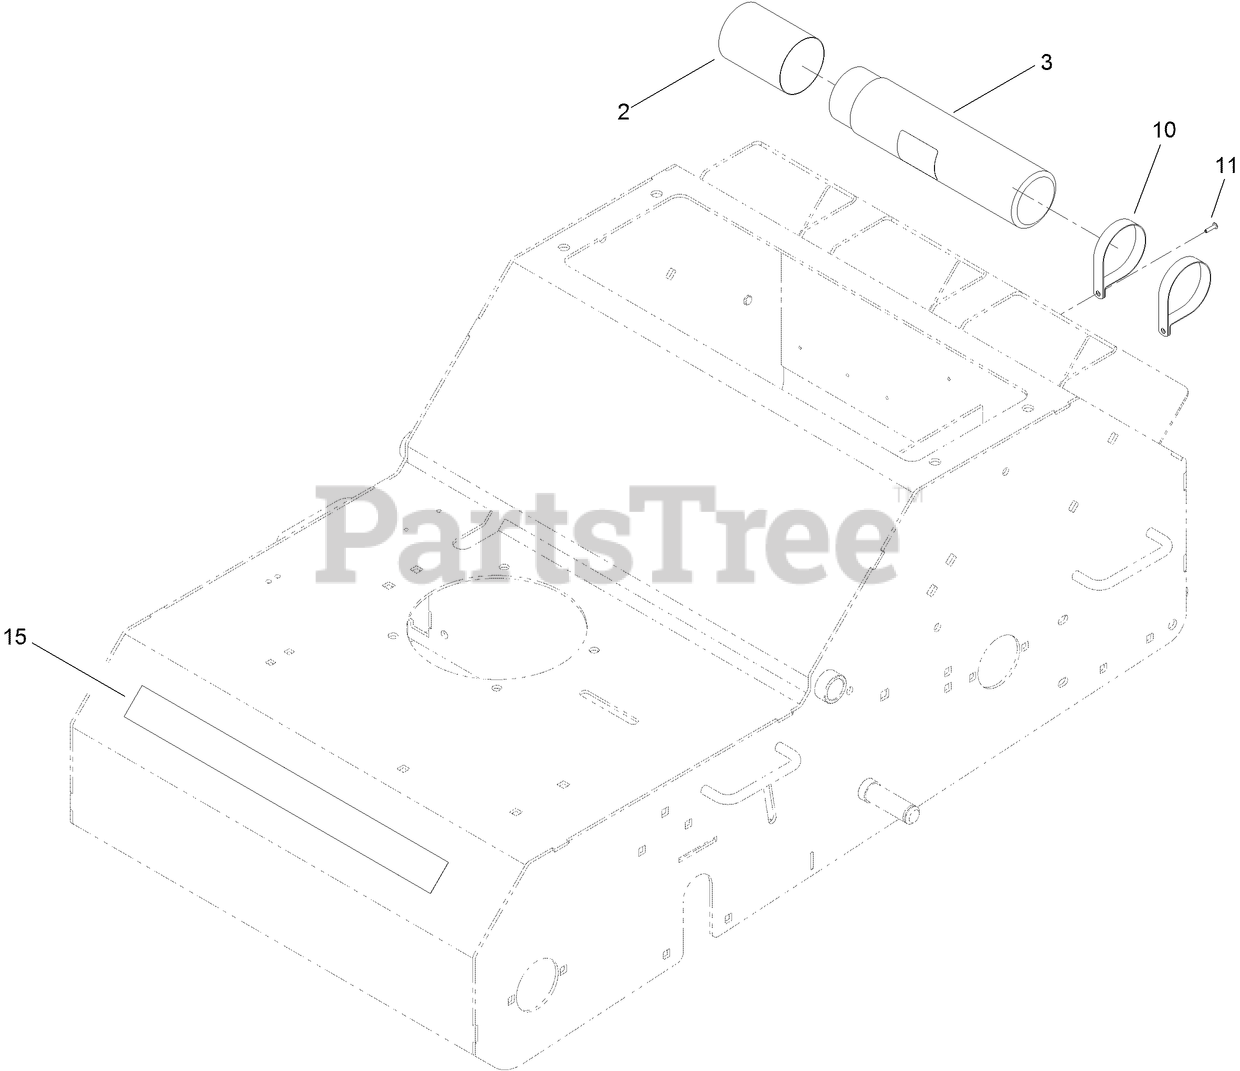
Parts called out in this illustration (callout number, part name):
2	CAP-HOUSING
3	TUBE-MANUAL
10	CLAMP-R
11	RIVET-POP
